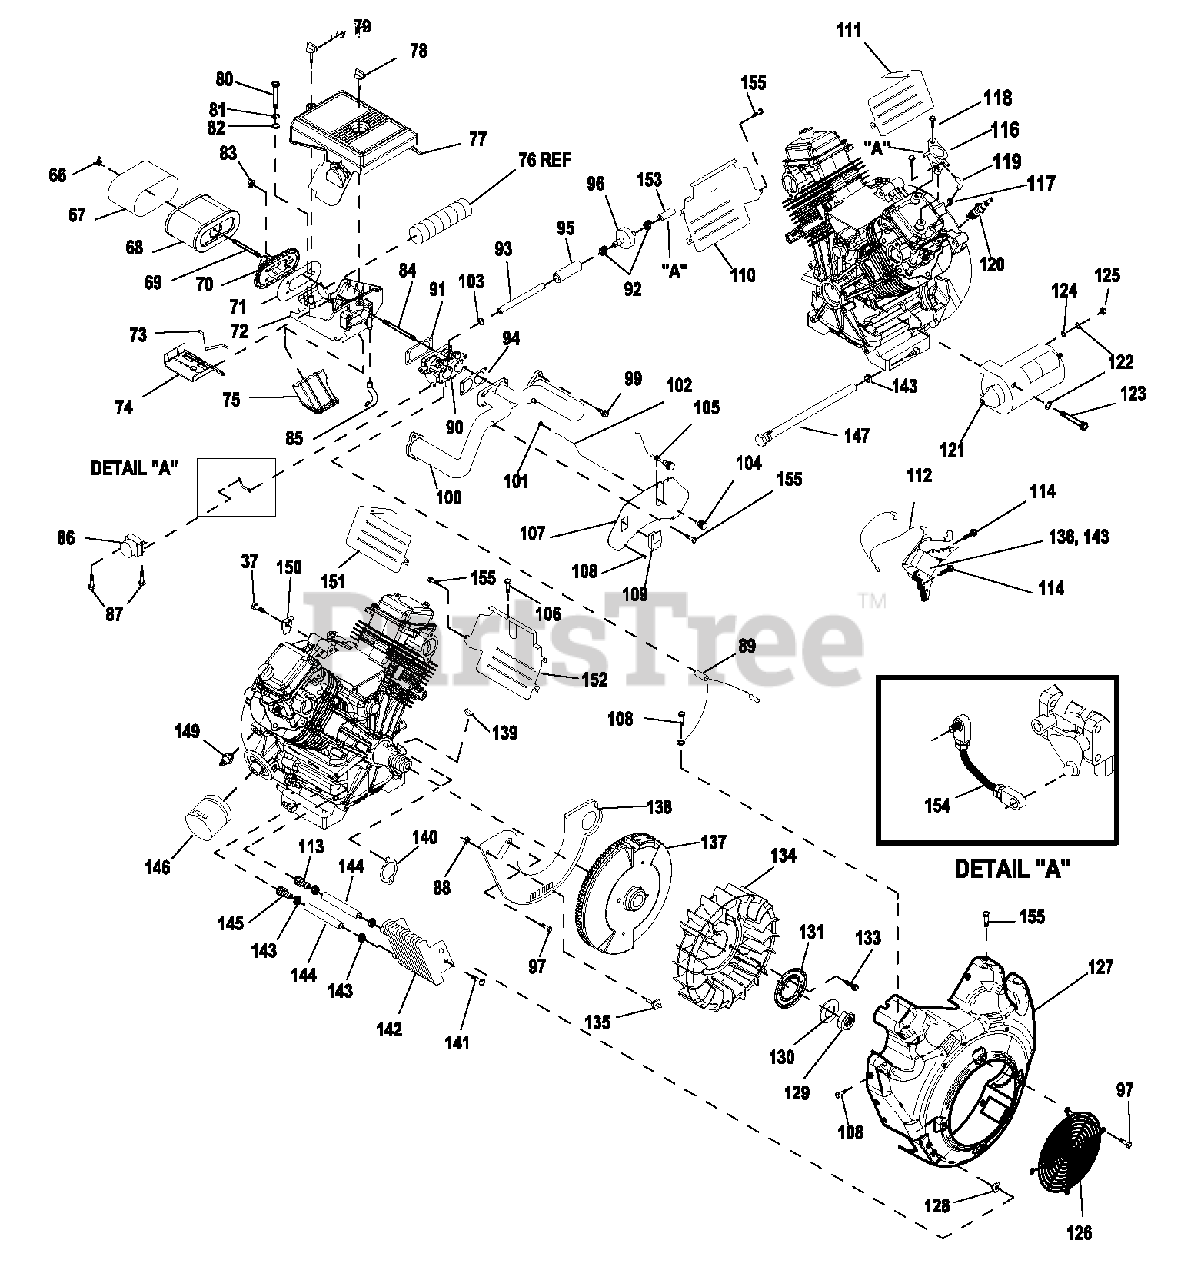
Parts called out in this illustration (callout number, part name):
66	WINGNUT, AIRBOX
67	PRECLEANER, AIR
68	ELEMENT, AIR CLEANER
69	STUD AIR FILTER 201 DRI-LOC
70	ADAPTOR, SPIT BACK
71	GASKET, SPITBACK
72	BASE, AIRBOX
73	SPRING, WINTER/SUMMER VALVE
74	VALVE, SUMMER / WINTER
75	SNORKEL, AIR INTAKE
76	TUBE, HEAT RISER 50.8 I.D.
77	COVER, AIRBOX
78	KNOB, AIRBOX 17mm
79	KNOB, AIRBOX 95MM
80	SCREW HHC M6-1.0 X 35
81	WASHER LOCK M6-1/4
82	WASHER FLAT 1/4
83	NUT, HEX FLANGE WHIZ M6-1.0
84	STUD, M6-1.0 X 105 DRI-LOC
85	HOSE, BREATHER
86	ASSY,CONTROLLER, GTH990 PORTABLE
87	SCREW HHTT M6-1.0 X 8
88	NUT, HEX LOCK M5-0.8 ZINC
89	ASSEMBLY, WIRE
90	CARBURETOR GTH990 W/BALL STUD
91	GASKET, CARB TO SPACER (GT-990)
92	CLAMP,HOSE OETIKR STEPLSS 14.5
93	HOSE 1/4 ID SAE 30R7 GREENBAR 9" PRE-CUT
94	GASKET, MANIFOLD TO CARBURETOR
95	SLEEVING, FLEXO HW 3/4 3"
96	FILTER, FUEL
97	SCREW, HHTT M6-1 x 10 LONG
98	NUT, HEX LOCK M5-0.8 ZINC
99	SCREW, SHC M8-1.25 x 25 LG SEMS
100	INTAKE MANF,HORIZ,2 BAR,MACH
101	NUT HEX M3-0.5
102	ROD, SUMMER / WINTER VALVE
103	CLAMP, HOSE WORM GEAR
104	KNOB, CONTROL SUMMER / WINTER, BLACK
105	CHOKE ASSEMBLY
106	SCREW TAPTITE M5-0.8 X 8 ZP
107	PANEL, CONTROL FACE PLATE
108	SCREW TAPTITE M6-1.0X 12 CLEAR ZINC
109	SWITCH ROCKER
110	WRAPPER, LOWER CYLINDER 2
111	WRAPPER, UPPER CYLINDER 2
112	ASSEMBLY, GROUND WIRE
113	EXTENDED BARBED STR 1/4 NPT X 3/8
114	SCREW HHTT M6-1.0 X 25 ZINC
115	ASSY IGN COIL NO ADV 760/990
116	PUMP, IMPULSE
117	CLAMP, HOSE BAND GREEN
118	SCREW, HHFCS M6-1.0 X 16 G8.8
119	ELBOW, RUBBER 90 DEG. GASOLINE
120	SPARKPLUG, CHAMPION RC14YC
121	STARTER MOTOR GEAR REDUCED
122	WASHER LOCK M8-5/16
123	SCREW HHC M8-1.25 X 85 G8.8
124	WASHER, FLAT M8
125	NUT, HEX M8-1.25 YELLOW ZINC
126	GUARD,FAN
127	HOUSING, BLOWER GAS COOLER
128	NUT, GROMMET 1/4 PLUG
129	NUT,HEX M24
130	WASHER, M24
131	PLATE, FAN
133	SCREW HHFCS M8-1.25 X 10 G8.8
134	FAN, NYLON
135	ASSY,GROUND WIRE CONNECTOR
136	ASSY IGN COIL NO ADV 760/990
137	FLYWHEEL ASSEMBLY
138	PLATE, BACKING GT990 WITH CUT OUT
139	KEY, WOODRFF 4 X 19D
140	GASKET, MANIFOLD / PORT
141	PLASTITE,1/4-15 X 3/4
142	COOLER, OIL
143	ASSY IGN COIL NO ADV 760/990
144	HOSE 3/8" 300PSI 6.5" LG OIL
145	BARBED STR 1/4NPT X 3/8
146	OIL FILTER, 90mm NO LOGO
147	ASSEMBLY, OIL DRAIN HOSE
149	SWITCH, OIL PRESS
150	BRACKET, AIRBOX SUPPORT
151	WRAPPER, UPPER CYLINDER 1
152	WRAPPER, LOWER CYLINDER 1
153	HOSE, 1/4" SAE 30R7 GREENBAR
154	ASSY, ROD, GOV. STEPPER MOTOR
155	SCREW HHFCS M6-1 X 12 G8.8
157	NUT, LOCK HEX M3-0.5 (GT-990)
